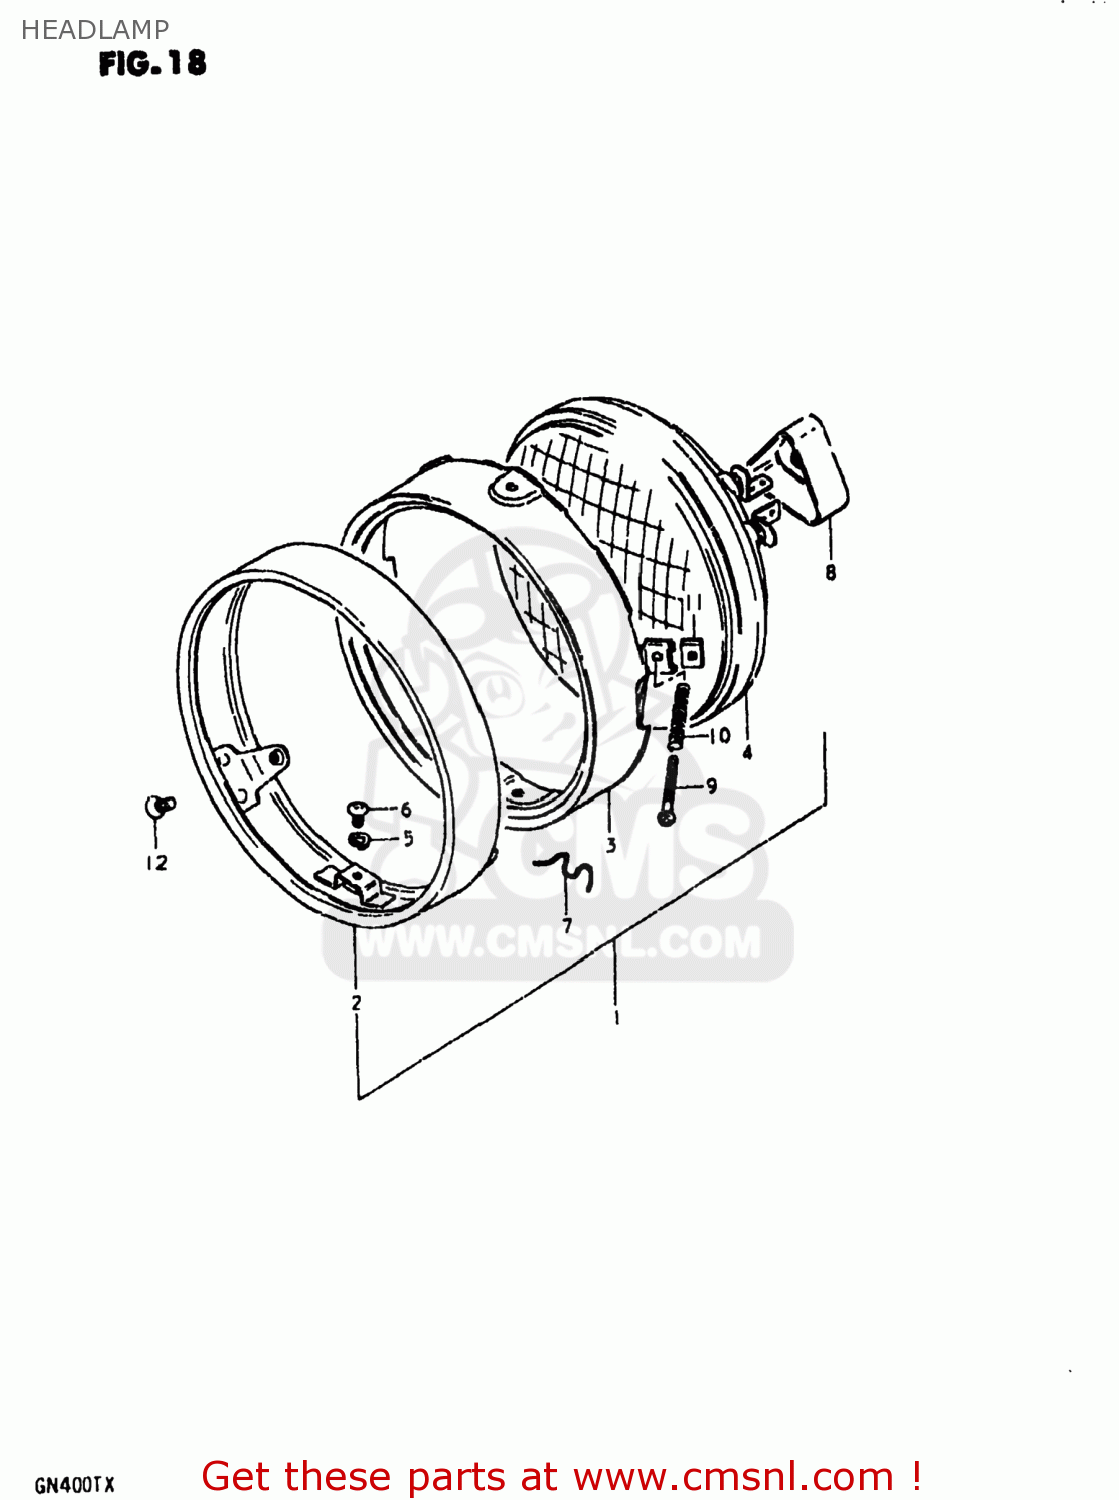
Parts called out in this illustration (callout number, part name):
1	HEADLAMP ASSEMBLY
2	RIM
3	RETAINER
4	LAMP UNIT
5	LOCK WASHER
6	SCREW
7	SPRING,HEAD LAMP UNIT
8	COVER
9	SCREW
10	SPRING
11	NUT
12	SCREW
